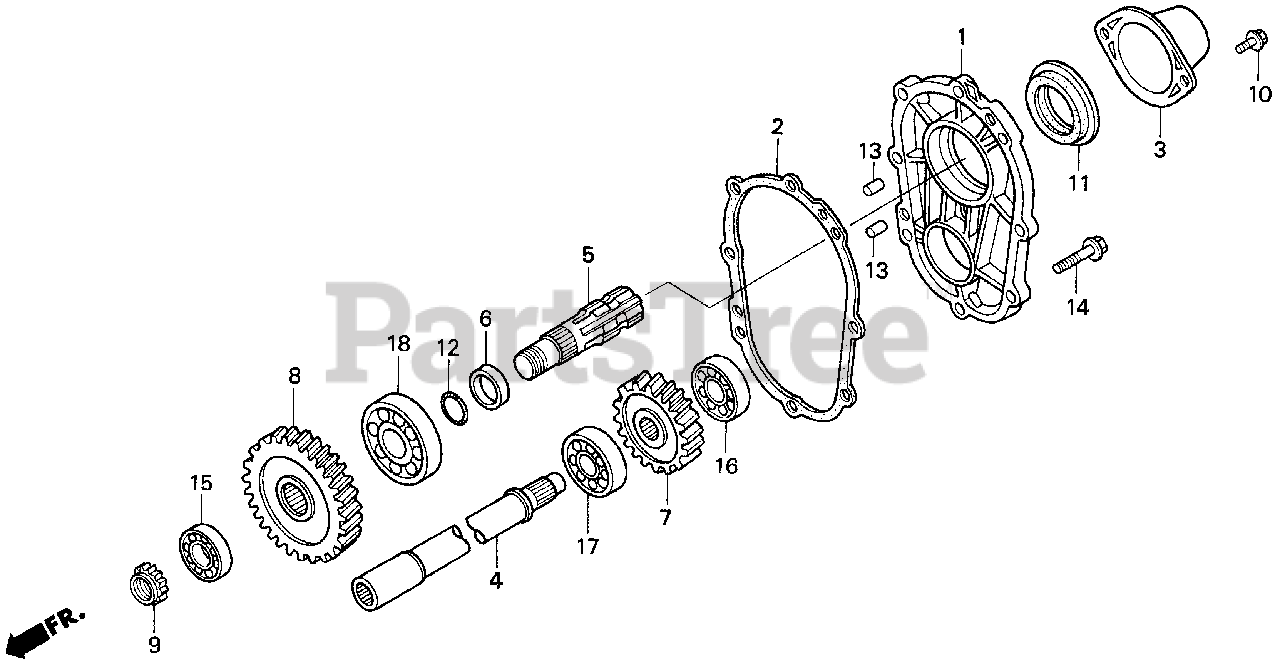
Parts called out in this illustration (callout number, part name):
1	COVER, RR. TRANSMISSION
2	GASKET, RR. COVER
3	COVER, P.T.O.
4	COUNTERSHAFT B, P.T.O.
5	SHAFT, P.T.O. OUTPUT
6	COLLAR, P.T.O.
7	GEAR, P.T.O. FINAL DRIVE (22T)
8	GEAR, P.T.O. FINAL DRIVEN (43T)
9	NUT, LOCK (25MM)
10	BOLT, SPECIAL (6MM)
11	OIL SEAL (40X55X8)
12	O-RING (29.7X2.4) (NOK)
13	PIN, DOWEL (8X14)
14	BOLT, FLANGE (8X32)
15	BEARING, RADIAL BALL (6205)
16	BEARING, RADIAL BALL (6304)
17	BEARING, RADIAL BALL (6305)
18	BEARING, RADIAL BALL (6306)
